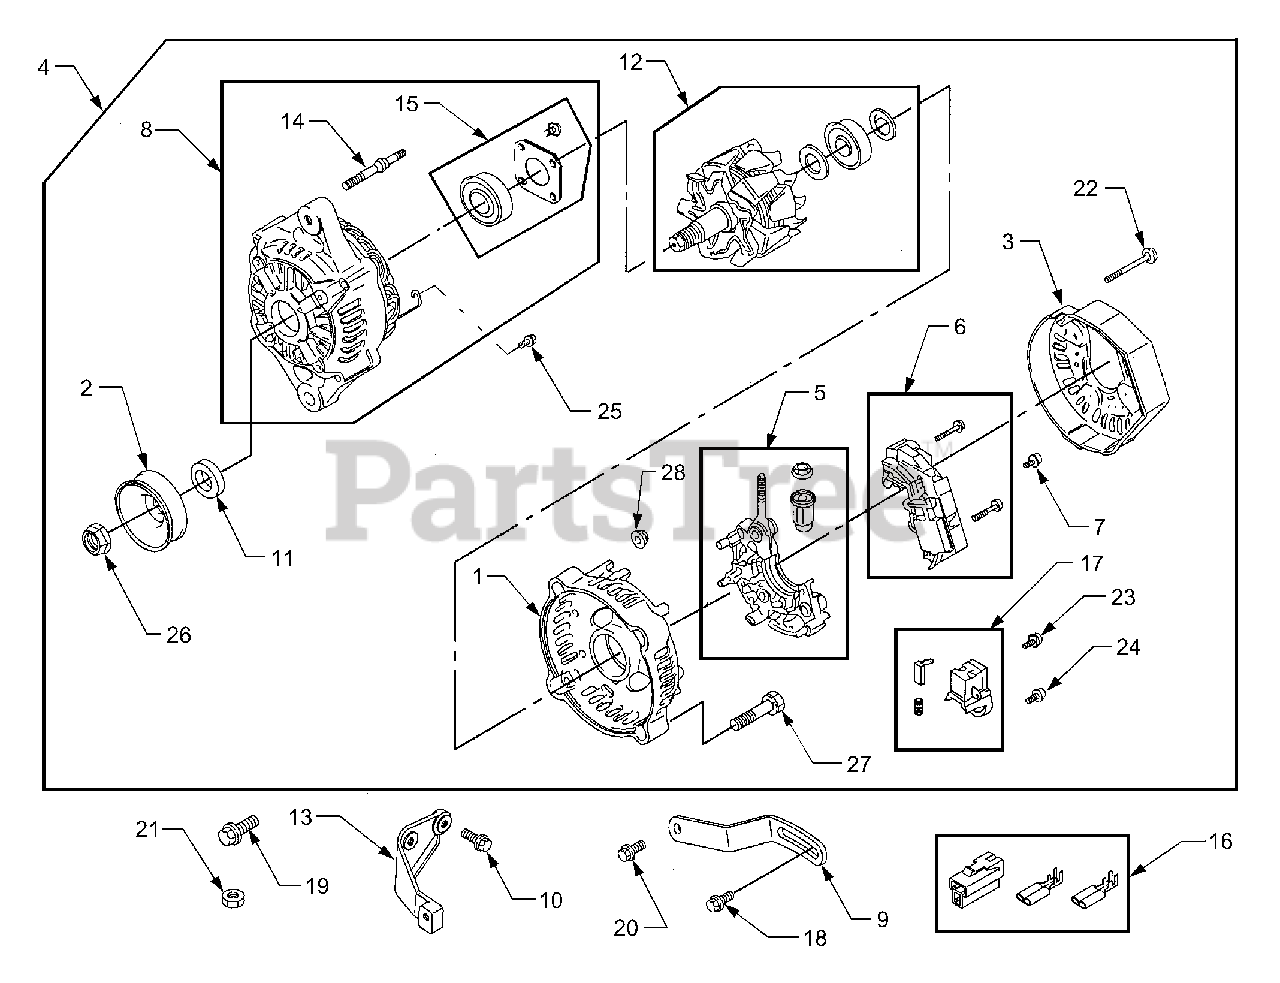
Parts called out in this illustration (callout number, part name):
1	Housing, Brush End
2	Pulley, Alternator
3	Cover, Brush
4	Alternator
7	Screw, Rectifier
8	Housing, Drive End
9	Strap, Adjusting
10	Screw, Support Bracket
11	Spacer, Support Bracket
13	Bracket, Support
14	Stud, Alternator
15	Retainer, Bearing
16	Connector, Terminal
17	Retainer, Brush
18	Screw, Alternator
19	Screw, Alternator
20	Screw, Adjusting Strap
21	Nut, Alternator
22	Screw, Brush Cover
23	Screw, Brush Retainer
24	Screw, Brush Retainer
25	Screw, Ground Terminal
26	Nut, Alternator Pulley
27	Screw, Brush End Housing
28	Nut, Brush End Housing
